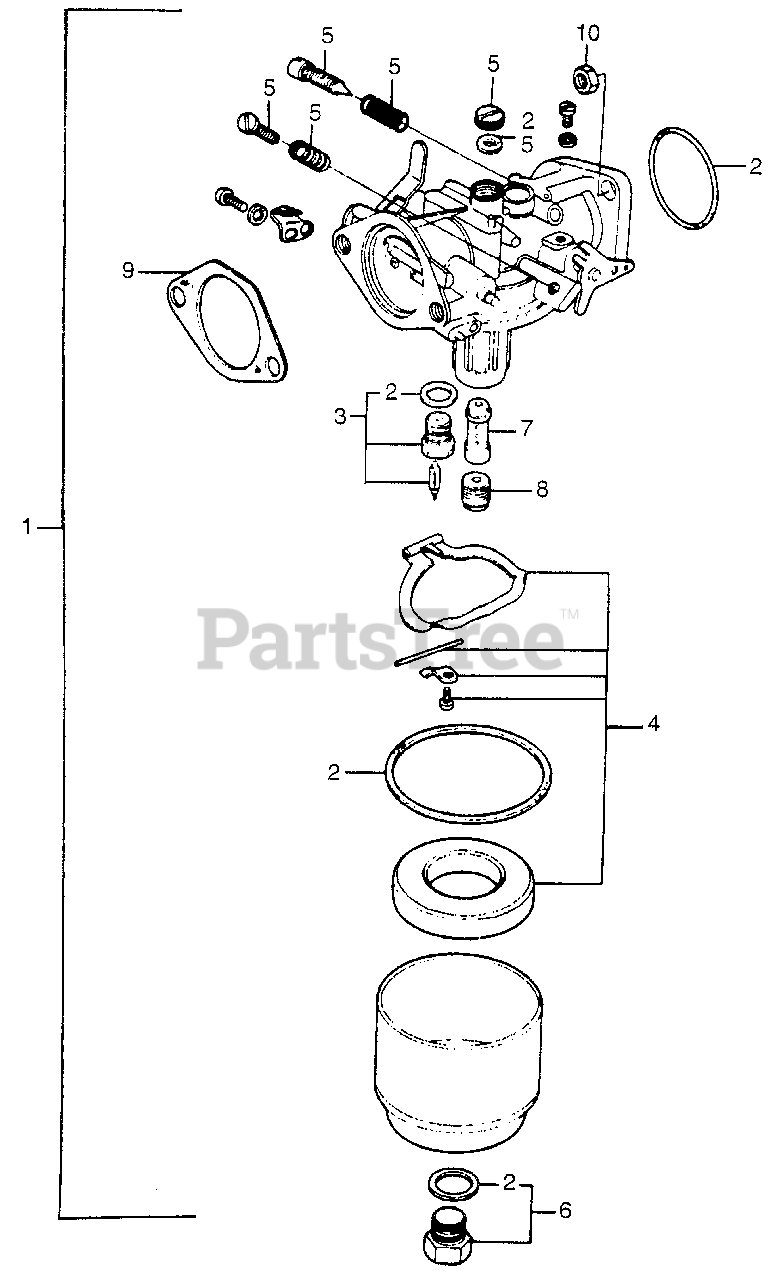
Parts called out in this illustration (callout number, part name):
1	CARBURETOR (N/A: SEE COMPONENTS)
2	GASKET SET
3	VALVE SET, FLOAT
4	FLOAT SET
5	SCREW SET A (NOT AVAILABLE)
6	SCREW SET (NOT AVAILABLE)
7	NOZZLE, MAIN (NOT AVAILABLE)
8	JET, MAIN (#80) (NOT AVAILABLE)
8	JET, MAIN (#78) (NOT AVAILABLE)
9	GASKET, AIR CLEANER (NOT AVAILABLE)
10	NUT, HEX. (6MM)
